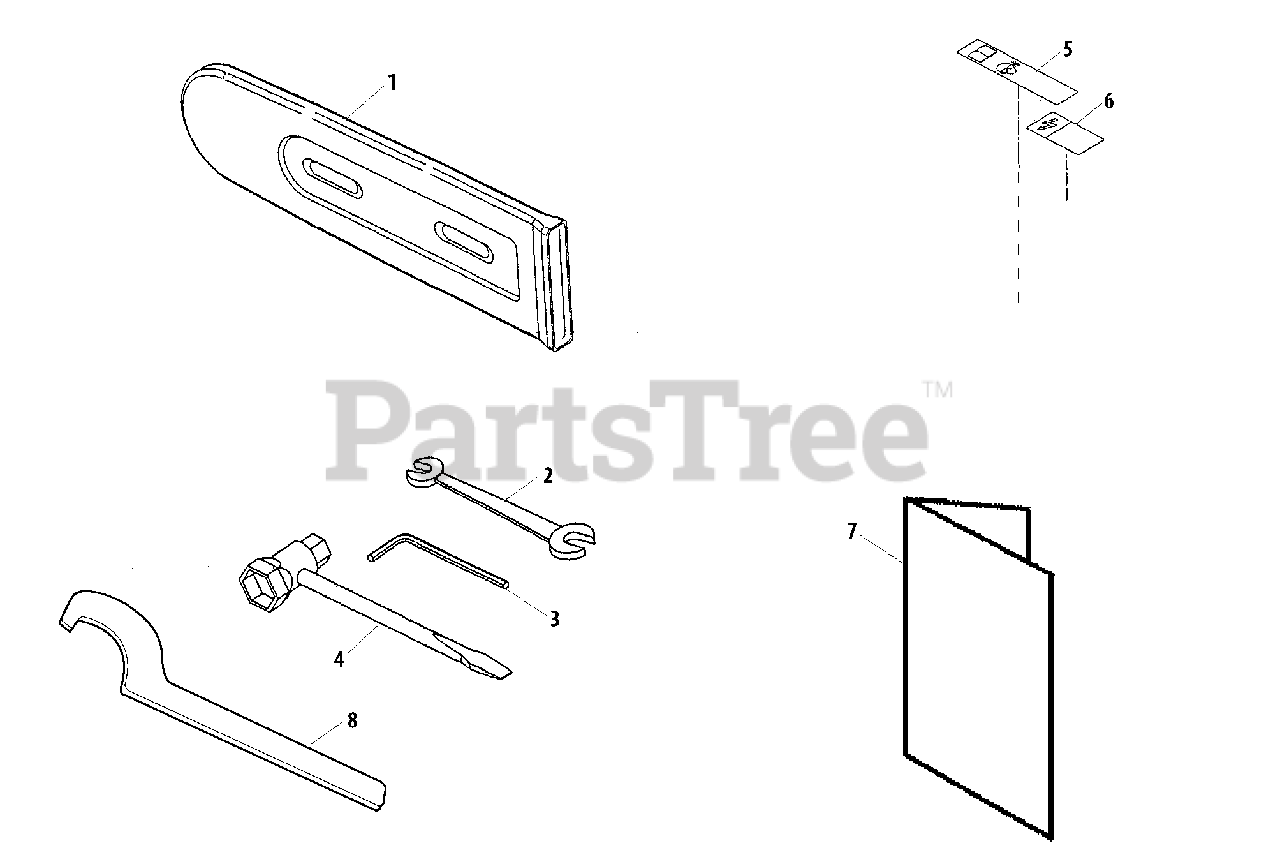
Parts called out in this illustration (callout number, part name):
1	COVER, GUIDE BAR
2	SPANNER - 8X10mm
3	HEX KEY - 4mm
4	T-WRENCH
5	LABEL - CAUTION
6	LABEL - CAUTION
7	OWNER'S MANUAL
8	HOOK SPANNER
